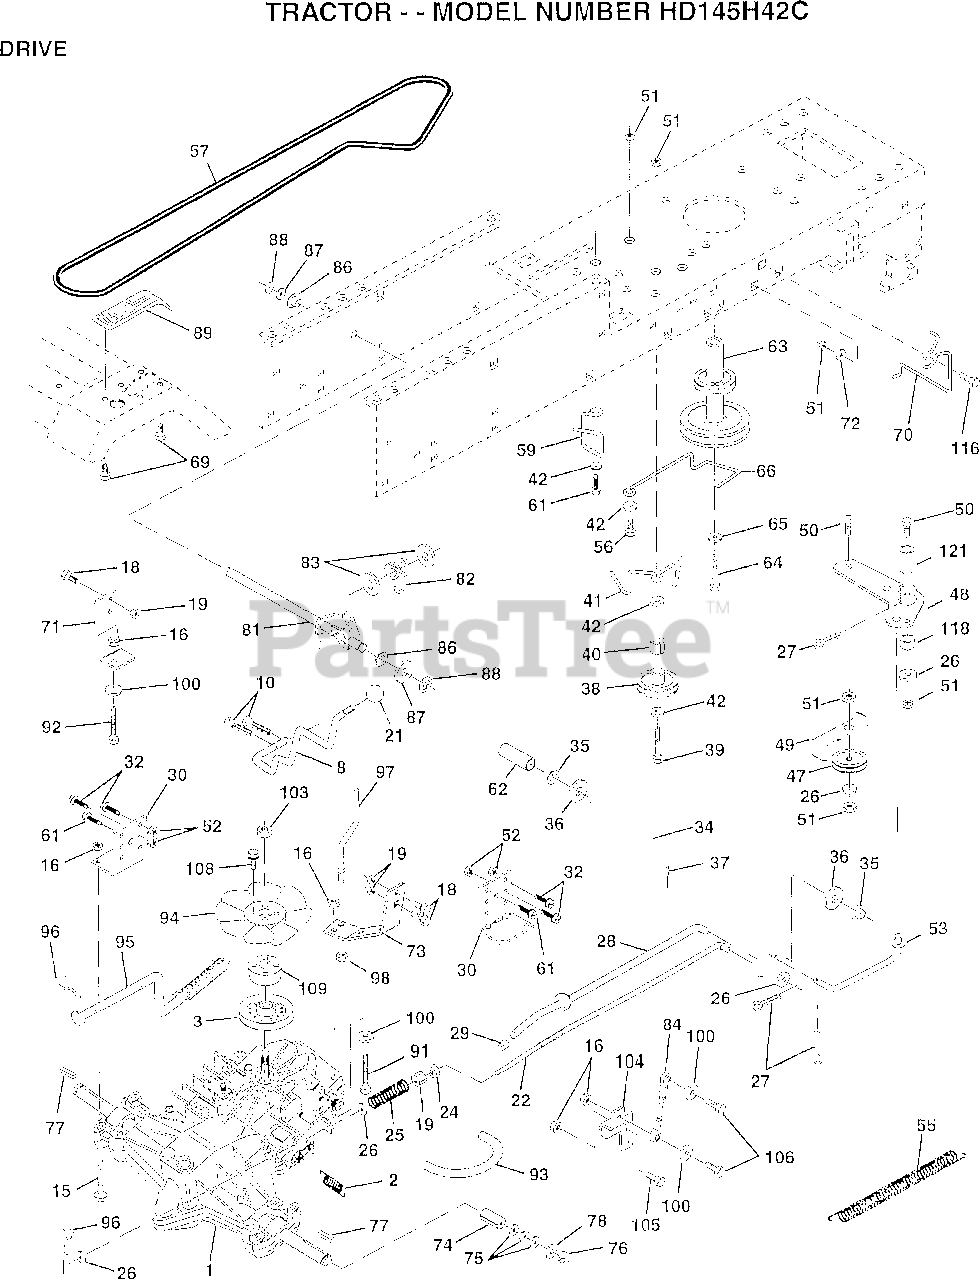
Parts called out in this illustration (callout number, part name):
1	TRANSAXLE HYD 0319-0500
2	SPRING RET BRAKE
3	PULLEY.4.20.HYDRO
8	ROD SHIFT FEND LT
10	PIN COTTER 1/8
15	BOLT.HX.FLG.5/16
16	NUT
18	BOLT
19	NUT
21	KNOB T (1/2-HOLE)
22	ROD.BRAKE.HYDRO.
24	NUT
25	SPRING ROD LT
26	WASHER
27	COTTER PIN
28	ROD.BRAKE.PARK.LT
29	PLUNGER CAP T
30	TRANSAXLE MTG BKT
32	BOLT
34	SHAFT ASM-PEDAL F
35	NYLON BEARING
36	WASHER LT
38	PULLEY.IDLER.FLAT
39	BOLT
40	SPACER T
42	WASHER
48	BELLCRANK ASM
49	RETAIN BELT
53	"LINK, CLUTCH T"
55	"SPRING, RETURN LT"
57	BELT-V.HYDR.84.61
59	KEEPER BELT CNTSP
61	SCREW
62	PEDAL COVER T
63	PULLEY.ENGINE
64	BOLT
65	LOCKWASHER
66	KEEPER-BELT
69	SCREW HEXWSH H-L
70	KEEPER BELT ENG
71	STRAP.TORQ.LH.HYD
72	WASHER
73	STRAP.TORQ.RH.HYD
74	SPACER SPLIT
75	WASHER
76	E-RING LT
77	SQUARE KEY
78	WASHER
81	SHAFT.CROS.500.HY
82	"SPRING,TORSION"
83	WASHER
84	ROD.TIE.BALL.HYD.
86	BUSHING
87	WASHER D
88	KLIP RING
92	HEX BOLT
93	"LINE FUEL HYD 4"""
94	"FAN 7"" HYDRO"
96	SPRING. RETAINER 1"
97	KEEPER.BELT.RH.HY
98	NUT
100	WASHER M
104	ARM.CONTROL.PUMP
105	SCREW CAP 5/16-18
106	BOLT
108	SCREW.HXHD.10-20
109	ADAPTOR.FAN.HYDRO
116	BOLT RDHD 3/8-16
118	SPACER-BELLCRANK
121	NYLINER-CLUTCHING
